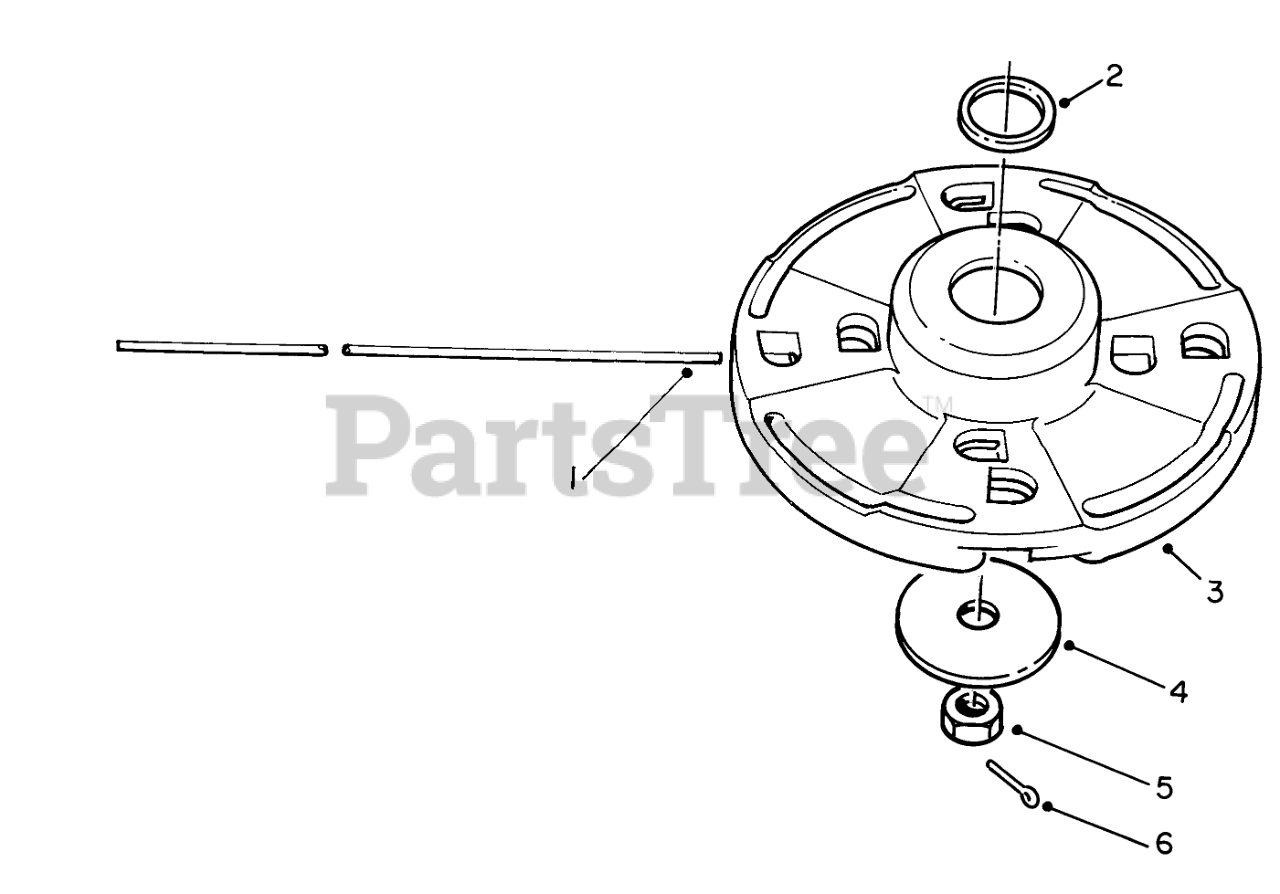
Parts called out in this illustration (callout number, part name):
1	Line-Cutting .105 Dia.
2	SPACER
3	Cutter Head Assembly (Incl. Ref. #2)
4	WASHER
6	1/16 X 1 LG COTTER PIN
